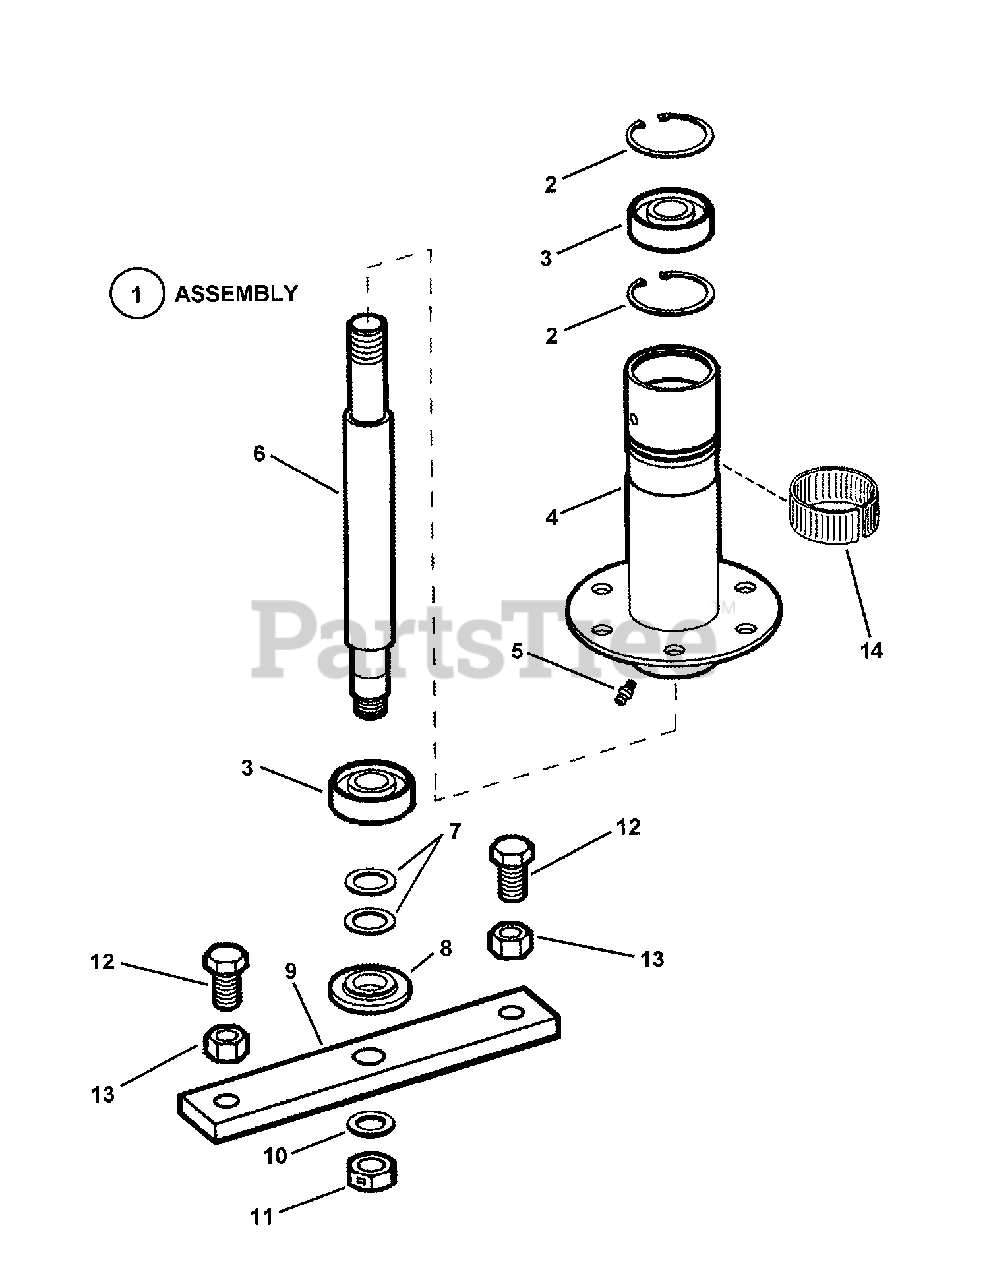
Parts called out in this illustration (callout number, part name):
1	ASSEMBLY, Spindle
2	RING, 1.85" Internal Retaining
3	BEARING, Spindle
4	WELDMENT, Spindle Housing (includes item #5)
5	LUBE FITTING, 3/16" Press-In
6	SPINDLE, Rider (10.327" overall length)
7	WASHER, .77 x 1.13 x .06 Flat
8	WASHER, Spindle
9	HOLDER, Blade (25" decks)
10	SPACER, Blade Centering
11	NUT, 5/8-18 Hex Center Lock Jam
12	SCREW, 1/2-20 x 1-1/4" Hex Head Cap, GR 5
13	NUT, 1/2-20 Hex, GR 5
14	RING, Tolerance
